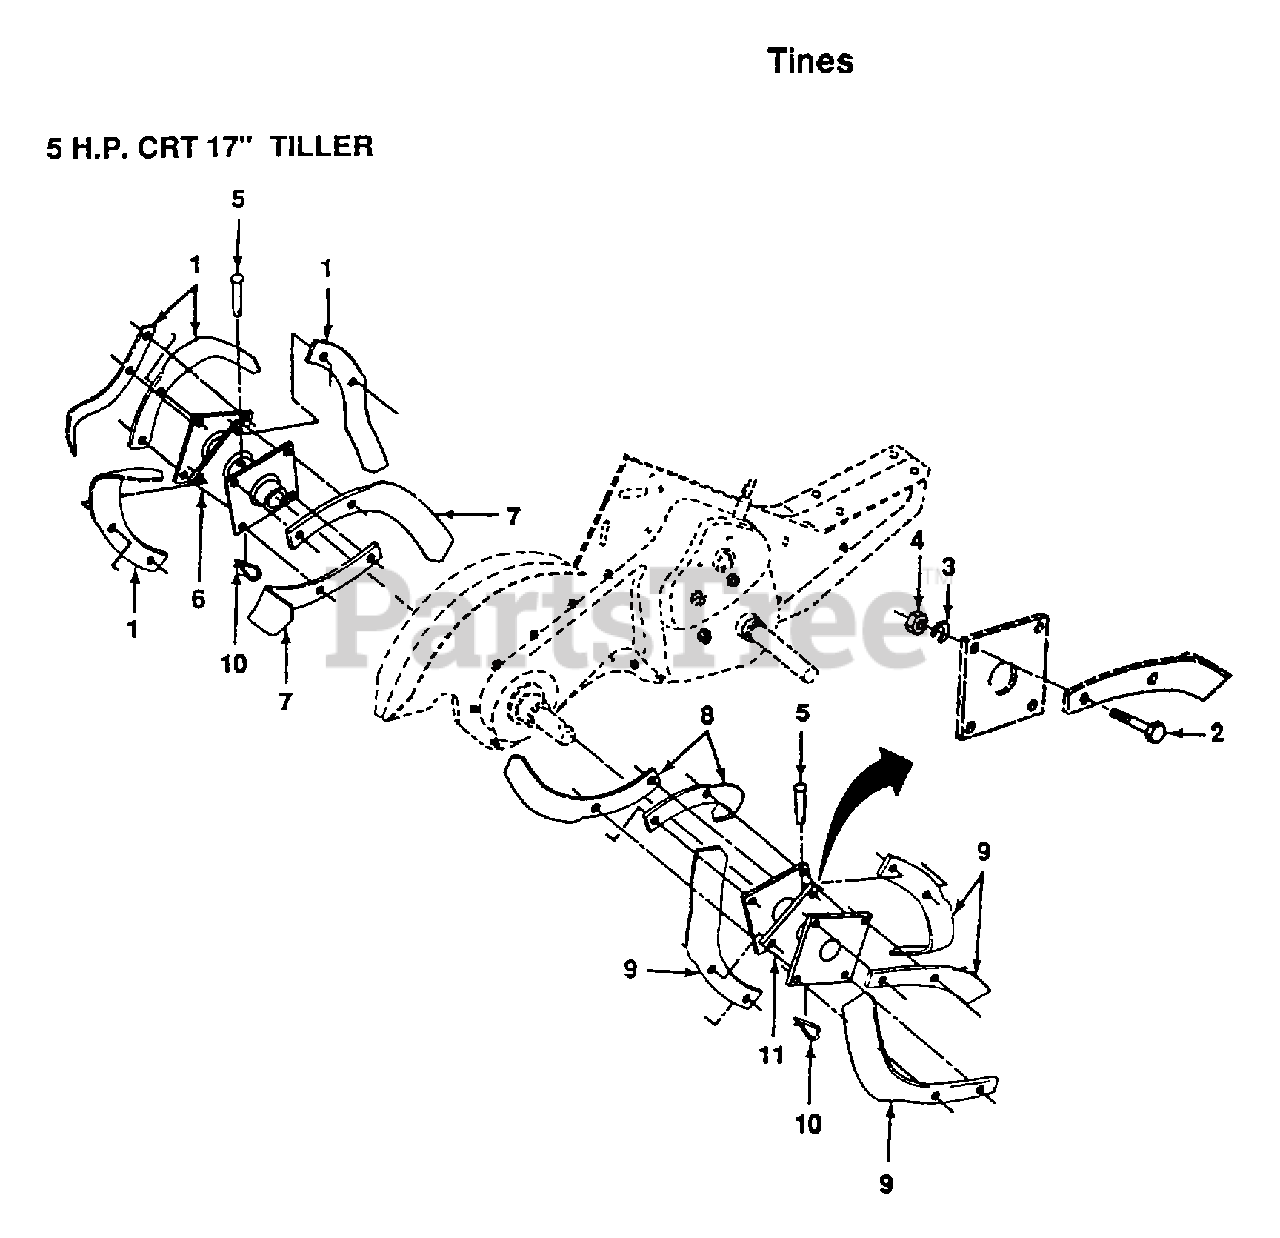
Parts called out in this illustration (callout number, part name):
2	BOLT
3	LOCKWASHER
5	RIVET.PAN HD.1.75
6	TINE ASSY LH CRT
7	"TINE.LH.12"""
8	"TINE.RH.12"""
10	RETAINER.SPRING
11	TINE ASSY RH CRT
